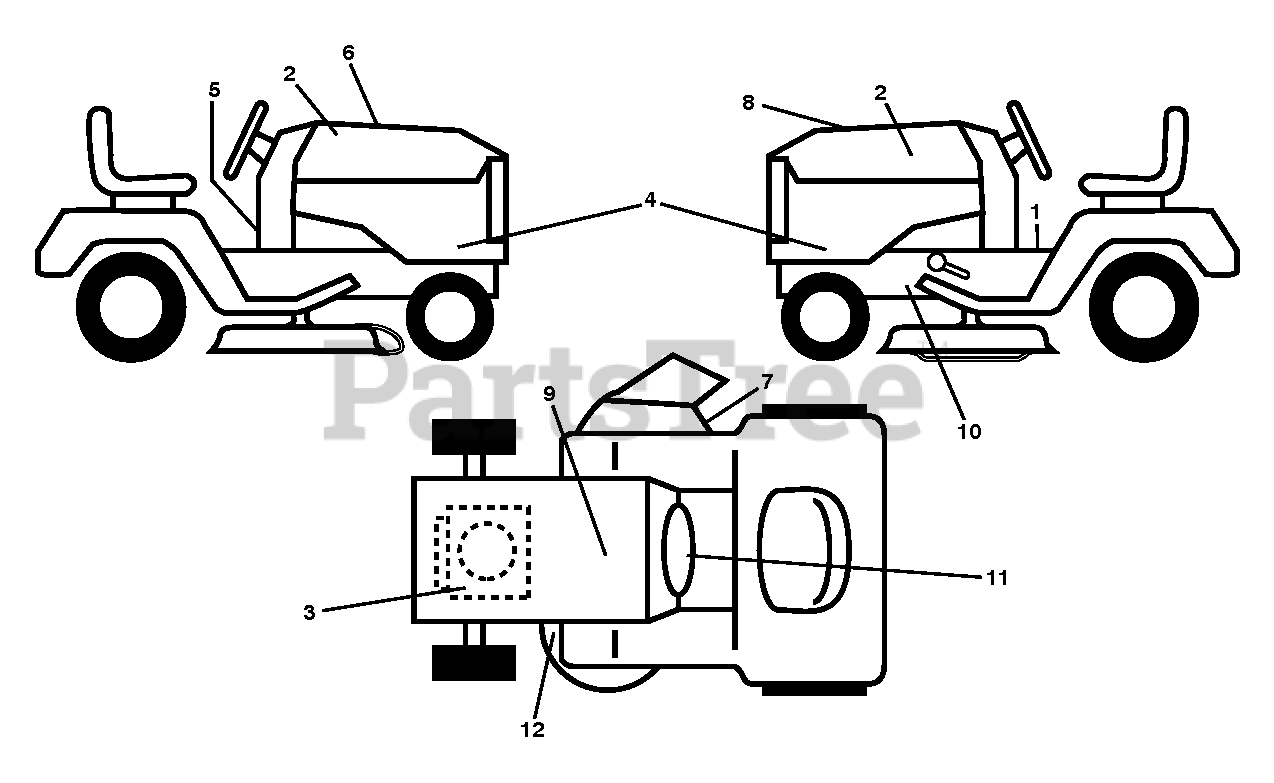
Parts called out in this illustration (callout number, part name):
1	DECAL.FENDER.WARNING
2	RP.DECAL.BADGE.170MM.TEXTLOGO
3	DECAL.ENG.BS.23HP.INTK.381207
4	DECAL.SIDE.PANEL.YTH23V42
5	DECAL, WARNING SPARK ARRESTOR
6	DECAL.REPLACEMENT.960430147.
7	DECAL.WARN.KEEP.HAND.AWAY
8	DECAL.WARNING.CUST.RESP.E85.
9	DECAL BTRY SYMBOLS
10	DECAL.PEDAL.HUSQ.CROWN
11	LABEL.EMISS.CALIF.HUSQVARNA
12	DECAL V BELT SCHEMATIC
